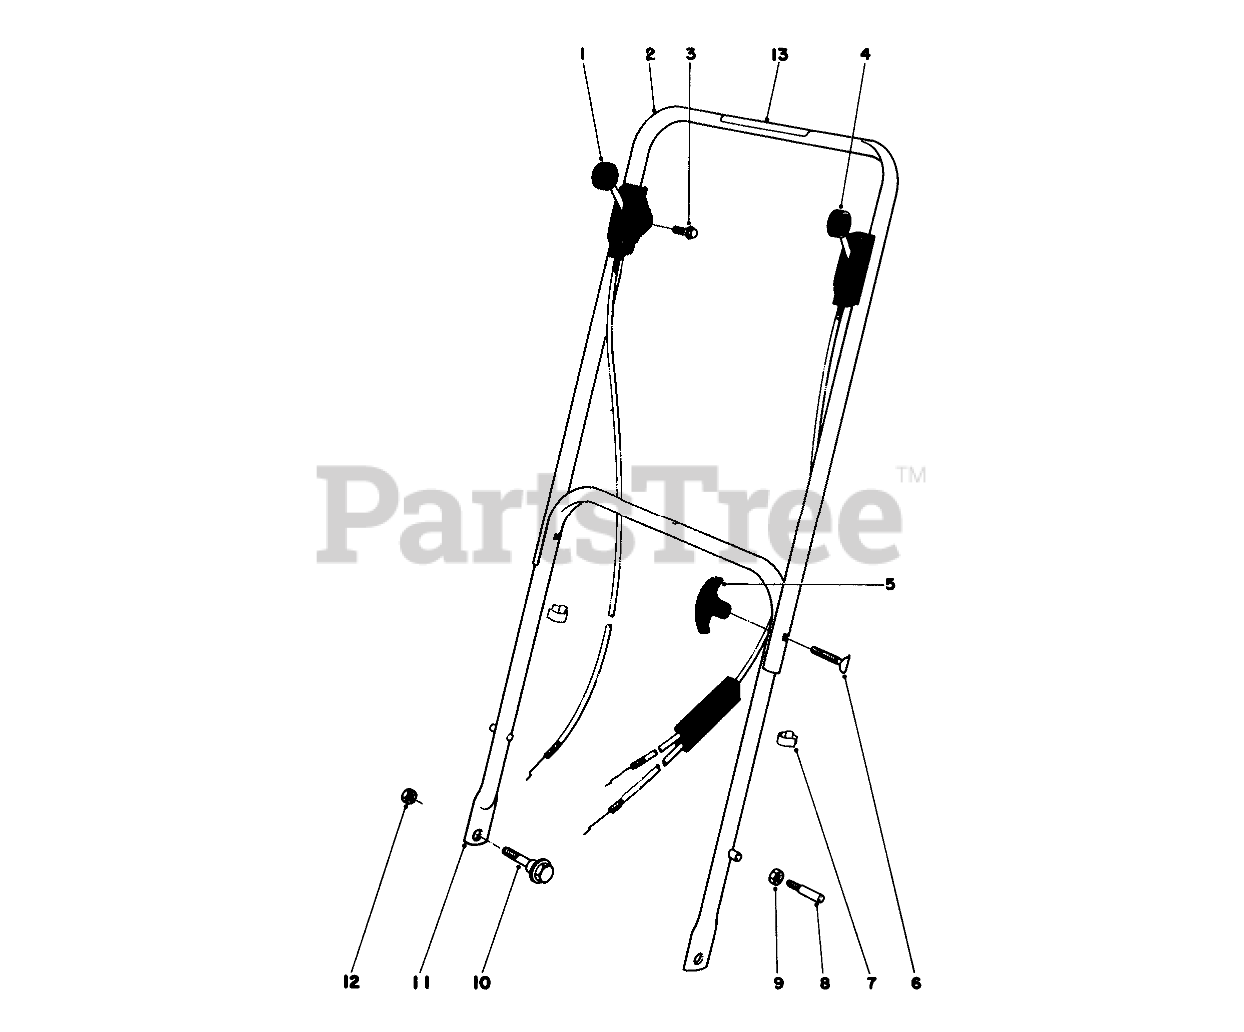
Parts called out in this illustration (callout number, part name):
1	Throttle Control
2	UPPER HANDLE
4	Traction Control
6	HANDLE SCREW
7	BOWDEN CLIP
8	HANDLE PIN
9	Nut
10	SCREW-SHOULDER
11	Lower Handle
12	Nut
13	Decal
